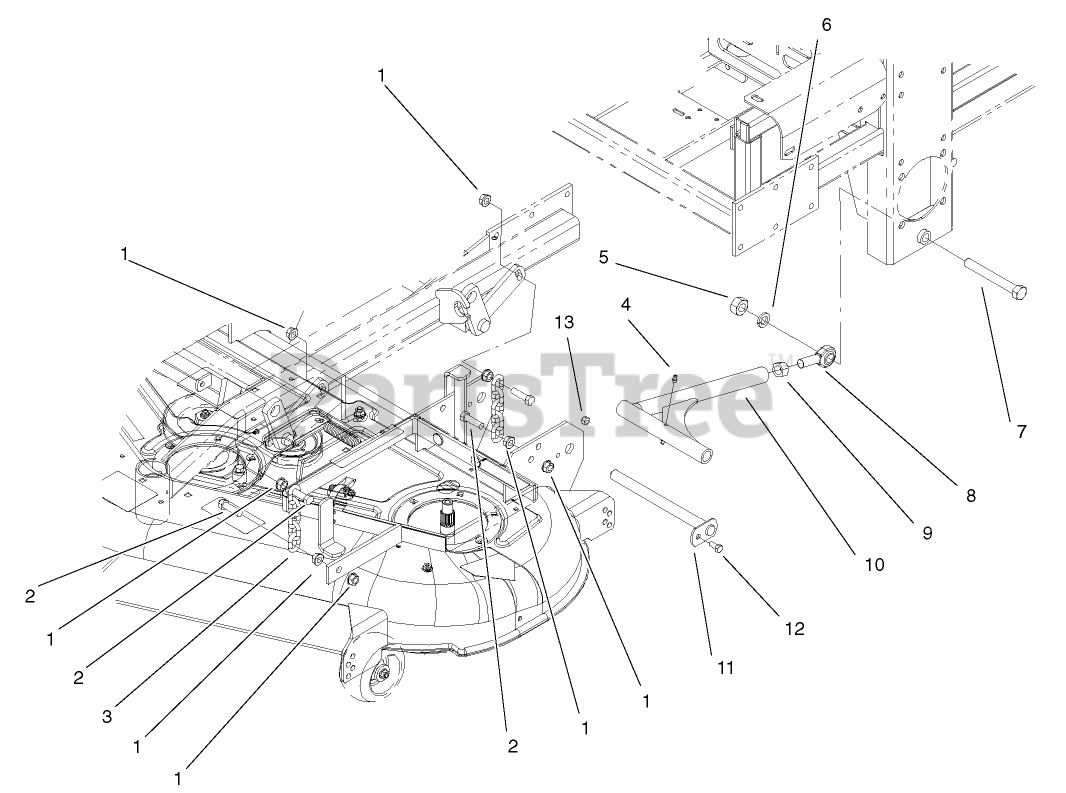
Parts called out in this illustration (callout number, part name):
1	NUT-HF
2	SCREW-CAP, HH
3	CHAIN-LIFT, DECK
4	FITTING-GREASE
5	NUT-HEX
6	WASHER-LOCK
7	SCREW-HH
8	BALLJOINT-SPHERICAL
9	NUT-HEX
10	STRUT
11	PIN-STRUT
12	SCREW-HH
13	NUT-LOCK, NI
